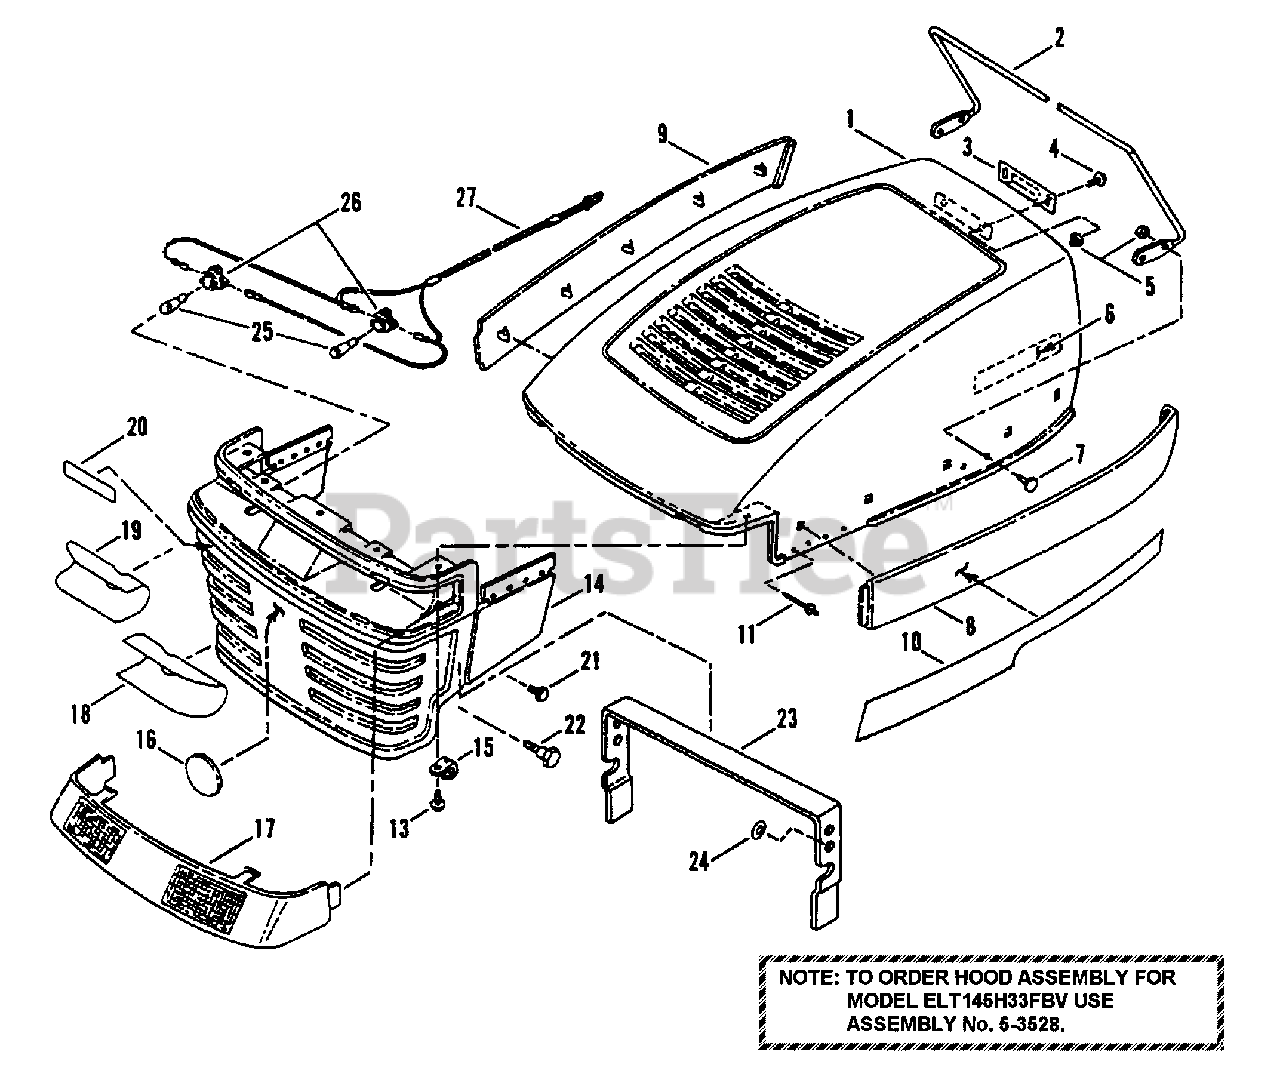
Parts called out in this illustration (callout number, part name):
1	HOOD
2	ROD, Hood Support
3	LATCH, Spring
4	SCREW, 1/4-20 x 5/8" Truss Head, Torx
5	NUT, 1/4-20 Hex Nyloc
6	DECAL - SNAPPER, 8" Molded Logo, Silver Letters
7	BOLT, 1/4-20 x 5/8" Flat Head Carriage, Grade 5
8	PANEL, Hood (Left Hand) (Black)
9	PANEL, Hood (Right Hand) (Black)
10	DECAL, Hood (Right Hand)
11	RIVET, 1/8" Pop
13	SCREW, M4.8 x 1.59 x 16.00MM, Special
14	GRILLE, Hood
15	CLIP, "J"
16	DECAL, Molded Medallion
17	LENS, Grille (Headlights)
18	DECAL, Reflect (Left Hand)
19	DECAL, Reflect (Right Hand)
20	DECAL - SNAPPER, 4" Molded Logo (Silver Letters - Blue Stripe)
21	SCREW, 5/16-18 x 1/2" Self-Tapping, Grade 5
22	BOLT, Shoulder, 3/8-16 x 1-1/4" Hex Socket, Torx
23	BRACE, Hood Support
24	RETAINER, 5/16" Bolt
25	BULB, Headlights
26	SOCKET, Headlight Bulb
27	HARNESS, Headlight Wiring
